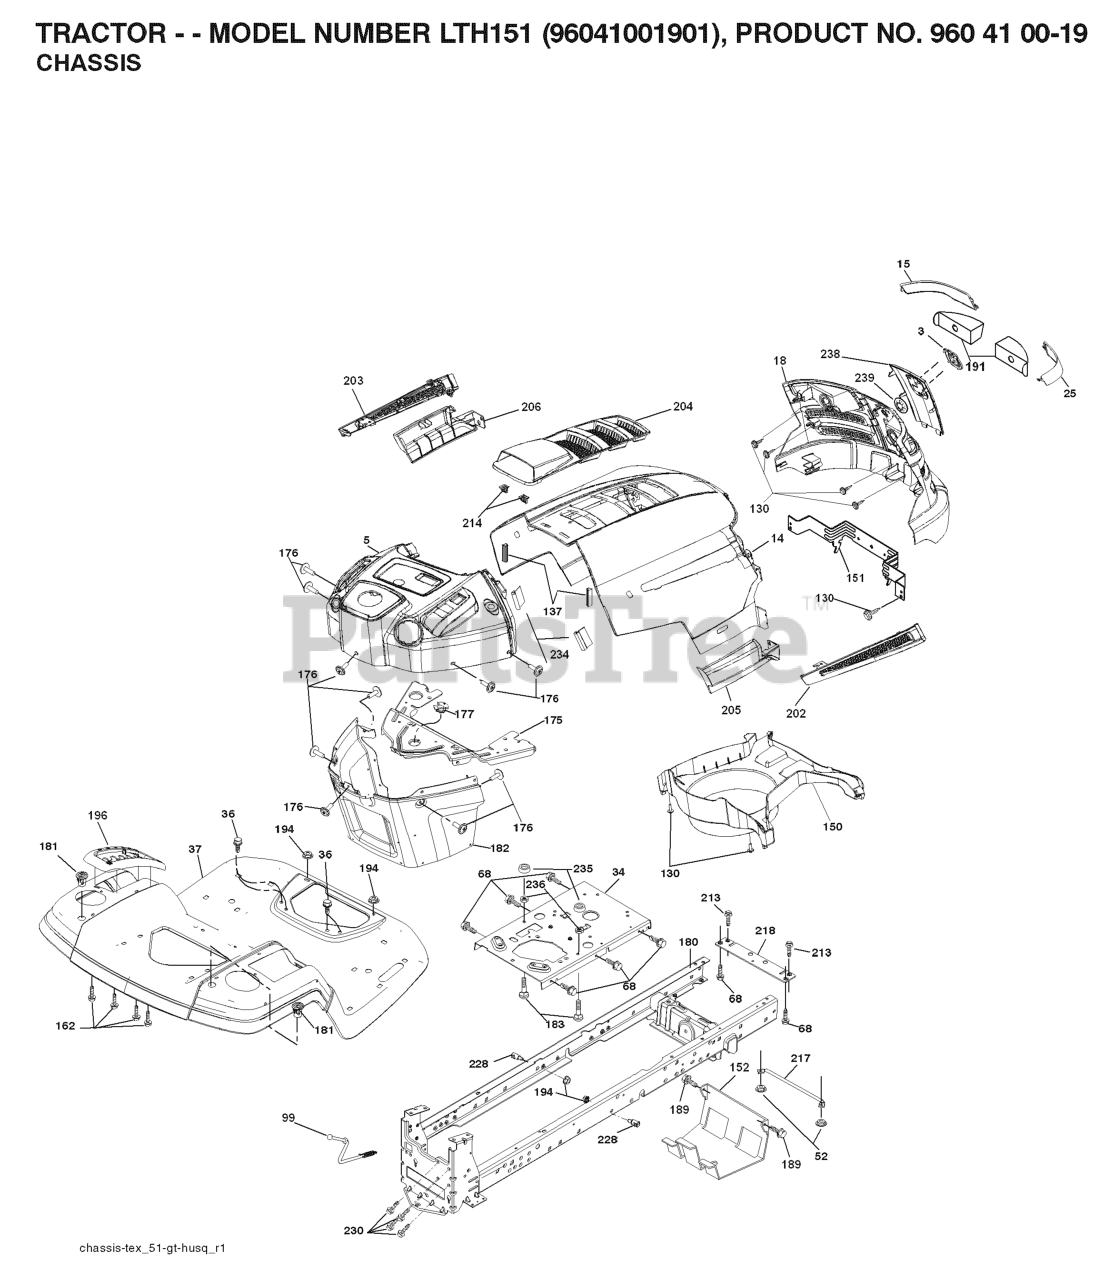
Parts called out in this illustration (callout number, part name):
3	RP LOGO
5	DASH
14	HOOD
15	LENS.HUSQVARNA LT.LH
18	RP GRILLE/LENS ASM.
25	LENS.HUSQVARNA LT.RH
34	PLATE.ENGINE.WELDED.CHASSIS
36	SCREW 5/16"
52	LOCKNUT
68	Screw 5/16-18 x 1/2 Hex, Self Tapping 5/16-18 x 1/2
99	ROD ASM BYPASS
130	SCREW
151	BRACKET PIVOT
152	SHIELD.BROWNING.W/TEX
175	CROSSMEMBER
176	SCREW.#10-24X5/8.RN.QU
177	BUSHING STEERING
180	CHASSIS
181	BUSHING.MNT.FEND.CRGO.
182	DASH LOWER
183	BOLT.5/16-18X1-1/4 FULL.THREAD
189	SCREW
191	INSERT REFLECTIVE
194	NUT LOCK HEX FLANGE 5/16-18
195	PLUG DASH
196	CONSOLE.ASM.DECK.LIFT.
202	VENT SIDE HOOD RH
203	VENT SIDE HOOD LH
204	VENT TOP HOOD
205	SKIRT SIDE RH
206	SKIRT SIDE LH
213	BOLT
214	CLIP.RETAINER.TINNER.
217	ROD.PIVOT.HOOD
218	X-PIECE.HOOD.STOP.NON/
222	SCREW.1/4-20X5/8
228	STUD.FASTNER.W/ANTI-ROTATE
230	SHOULDER BOLT 5/16-18TT
234	BUMPER.HOOD.TEX.HUSQVARNA
235	SPACER FENDER
236	NUT.CENTERLOCK.5/16-
238	TRIM
